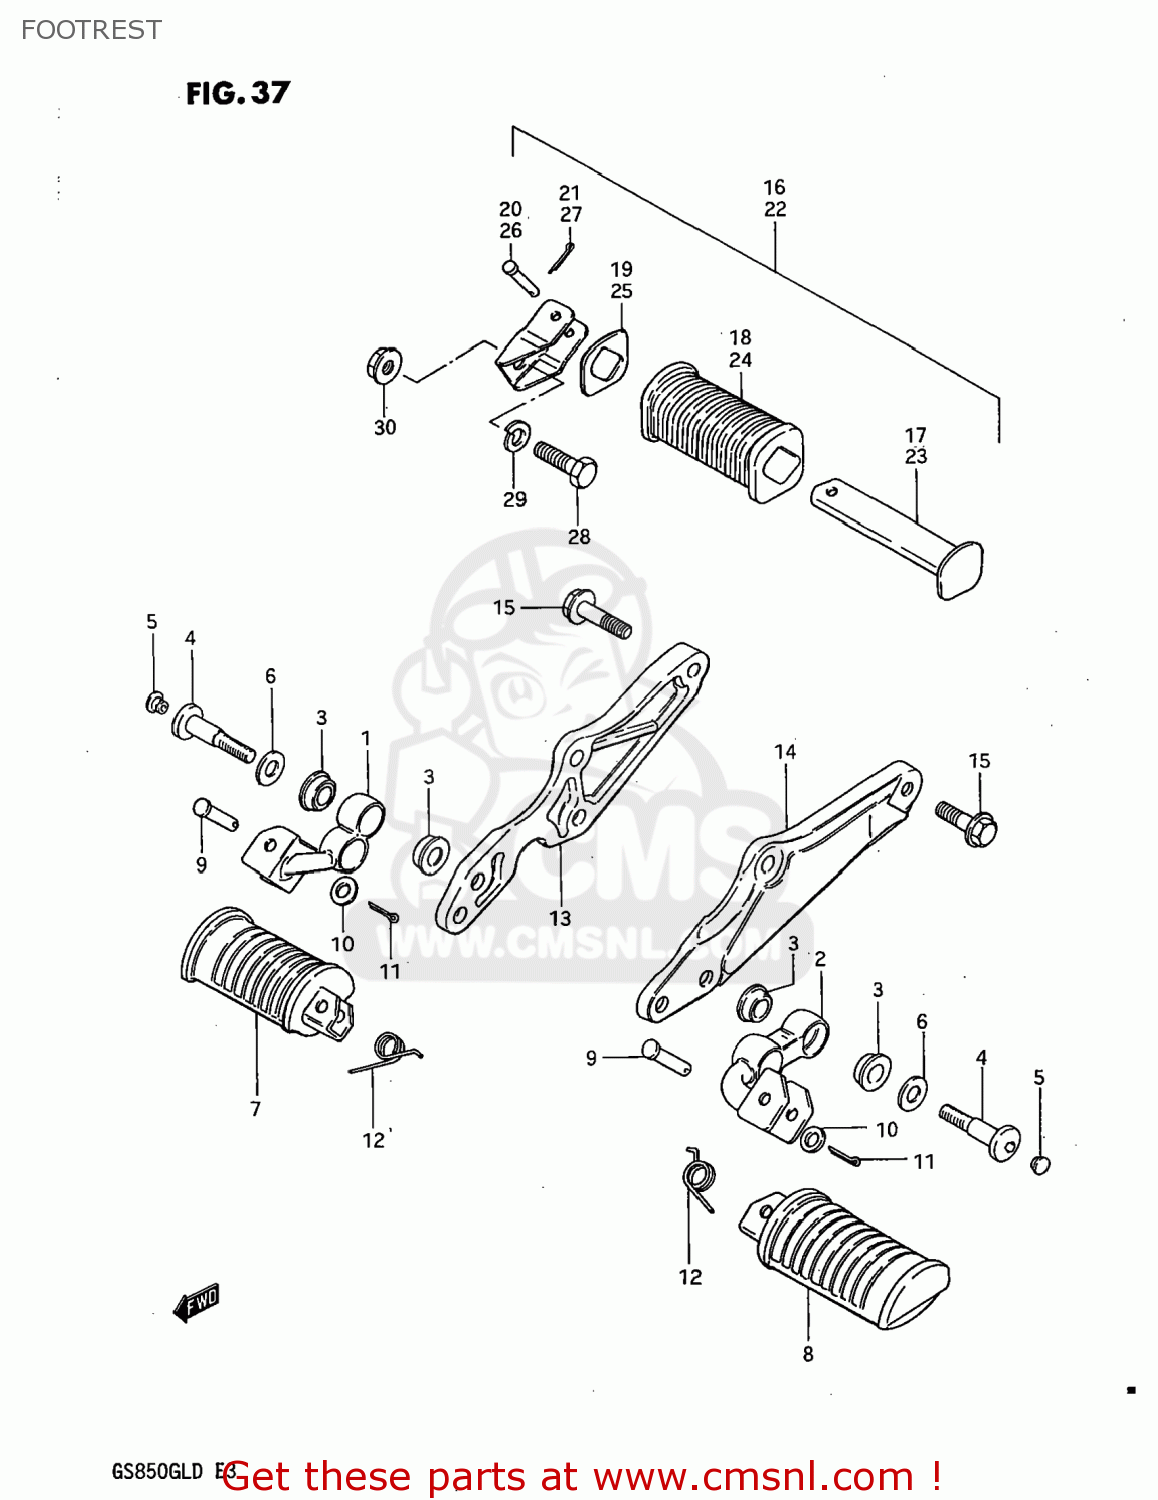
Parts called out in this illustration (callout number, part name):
1	BAR,FRONT FOOTREST
2	BAR,FRONT FOOTREST,LEFT
3	BUSH
4	BOLT
5	CAP
6	WASHER(10.5X28X2.3)
7	RUBBER,FRONT FOOTREST
8	FOOTREST
9	PIN
10	WASHER
11	PIN 20X20
12	SPRING
13	BRACKET
14	BRACKET
15	BOLT
16	FOOTREST ASSEMBLY,PILLION
17	BAR,REAR FOOTREST,LEFT
18	RUBBER,PILLION FOOTREST
19	WASHER,FOOTREST RUBBER
20	PIN
21	PIN
22	FOOTREST ASSEMBLY,REAR
23	BAR,REAR FOOTREST
24	RUBBER,REAR FOOTREST
25	WASHER,REAR FOOTREST RUBBER
26	PIN
27	PIN 20X20
28	BOLT,M10X1.25X
29	LOCK WASHER
30	NUT
